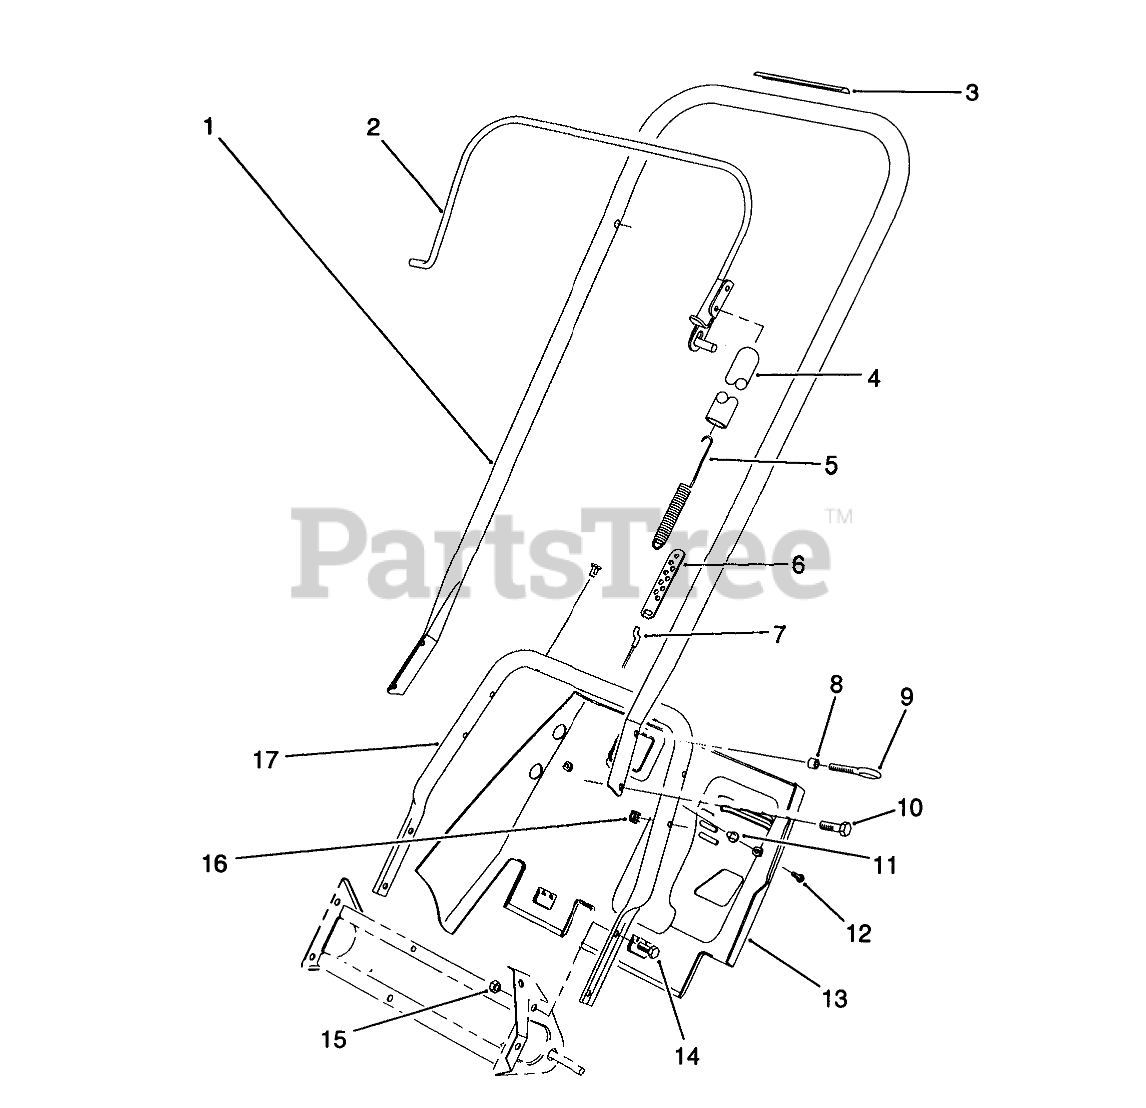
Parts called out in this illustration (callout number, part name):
1	Handle-Upper
2	Bail
3	DECAL - ROTOR DRIVE
4	COVER-SPRING
5	SPRING-CLUTCH
6	ADJUSTER-CABLE, CLUTCH
7	CABLE-CLUTCH
8	SPACER-BLADE, ROTOR
9	EYEBOLT
10	SCREW-HEX HD SLOT
11	EXPANSION TYPE FASTENER
12	SCREW-SHWH, THREAD FORMING
13	LOWER SHROUD
14	SCREW-HH
15	NUT-LOCK, NI
16	TINNERMAN NUT
17	Handle-Lower
